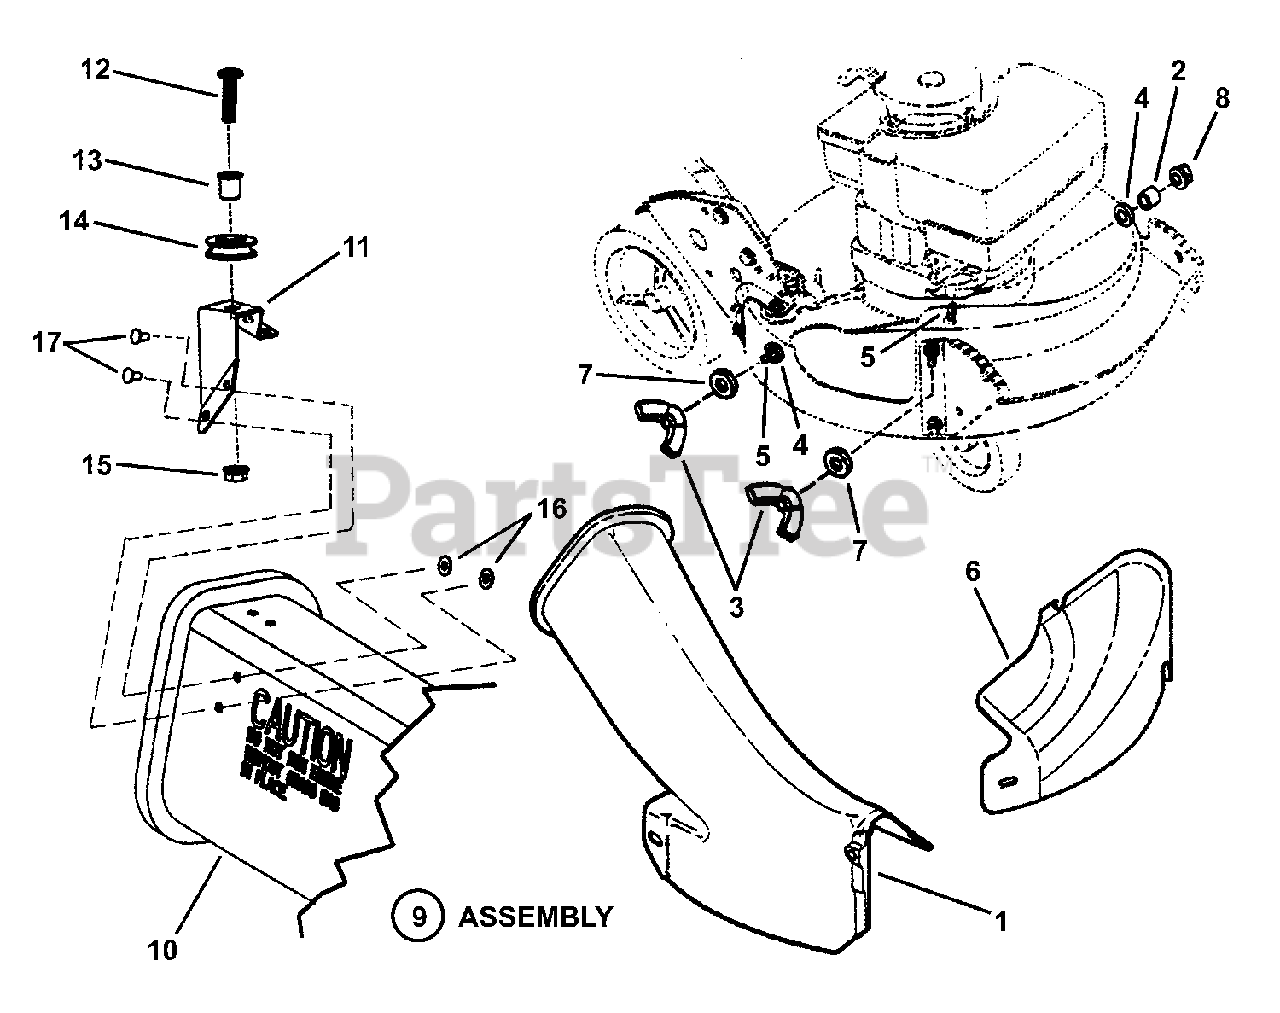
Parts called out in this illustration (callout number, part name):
1	ADAPTER, Grass Bag
2	SPACER, .316 I.D. x .375 O.D. x .310 thick
3	NUT, 5/16-18 Wing (Nylon Patch)
4	RETAINER, 5/16" Bolt
5	BOLT, 5/16-18 x 3/4" Short Neck Carriage GR5
6	COVER, 21" Deck
7	WASHER, 5/16" Flat
8	NUT, 5/16-18 Hex Large Flange Center Lock
9	ASSY, Grass Bag Adapter (Incl. items 11 thru 18)
10	ADAPTER, Grass Bag
11	BRACKET, Rope Pulley
12	SCREW, 5/16-18 x 1-1/4" Pan Head Machine
13	BUSHING, Flange
14	PULLEY, Plastic
15	NUT, 5/16-18 Hex Flange Lock GR5
16	WASHER, 15/32" Flat
17	RIVET, 3/16 x .344
